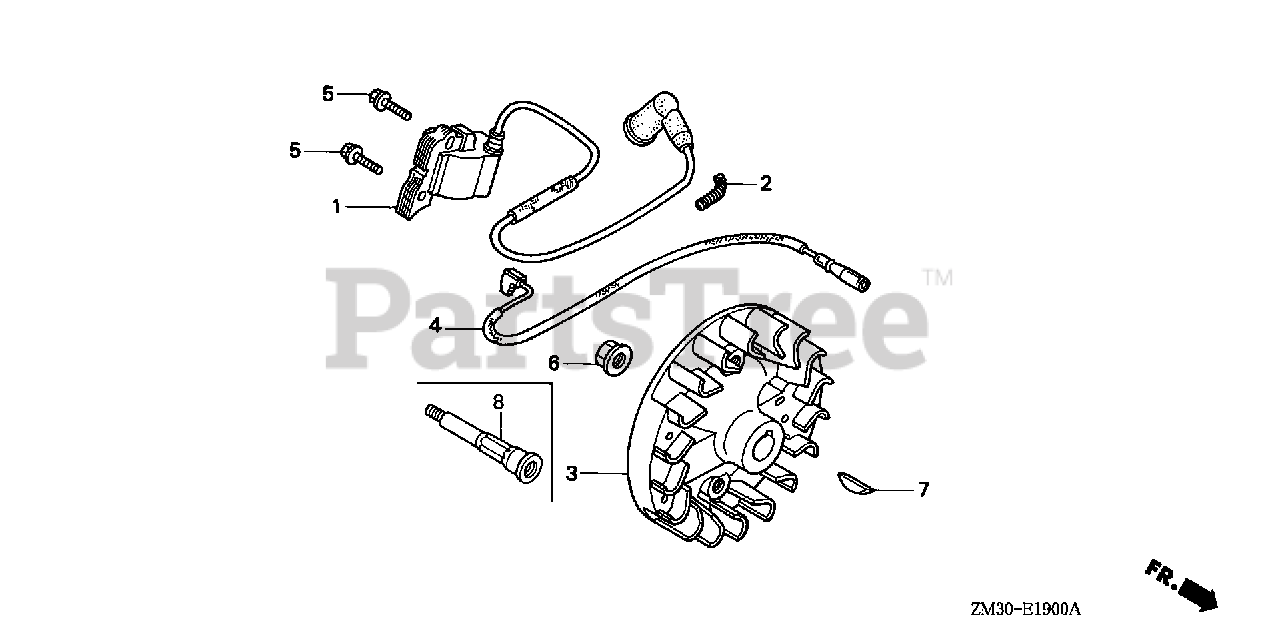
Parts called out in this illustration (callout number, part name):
1	COIL ASSY., IGNITION
2	TUBE A, CORRUGATED (7X18)
4	WIRE, STOP SWITCH
5	BOLT-WASHER (5X16)
6	NUT, FLANGE (10MM)
7	KEY, WOODRUFF (16X12)
